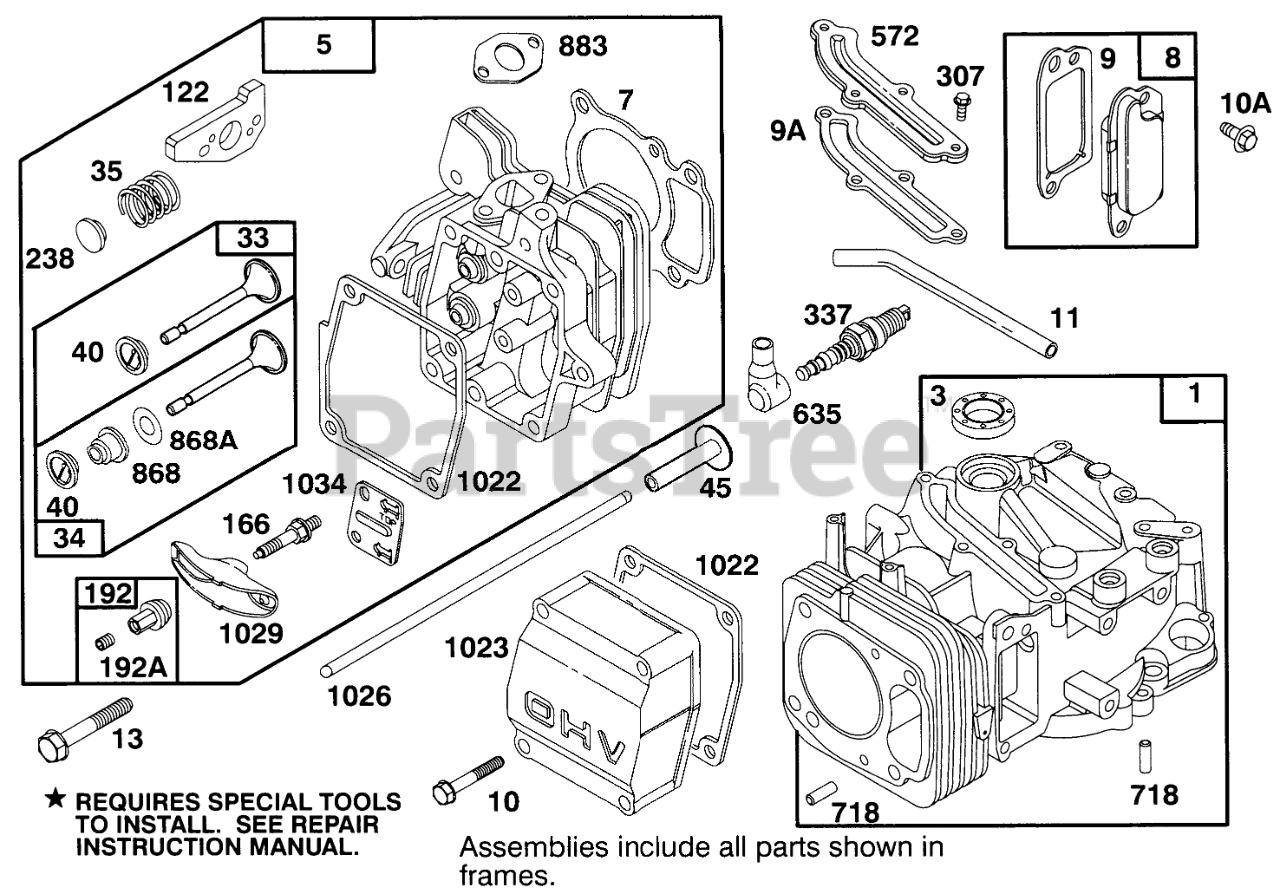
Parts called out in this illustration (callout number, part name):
1	CYLINDER ASSEMBLY
3	SEAL - OIL
5	CYLINDER HEAD
7	CYLINDER HEAD GASKET
8	Breather Assy
9	BREATHER GASKET
9A	GASKET-BREATHER
10	HEX HEAD SCREW
10A	HEX HEAD SCREW
11	TUBE - BREATHER
13	CYLINDER HEAD SCREW
33	EXHAUST VALVE
34	INTAKE VALVE
35	VALVE SPRING
40	SPRING RETAINER
45	VALVE TAPPET
122	ADAPTER ASSEMBLY
166	ROCKER ARM STUD
192	NUT - HEX SPECIAL
192A	SCREW SET
238	VALVE CAP
307	SCREW - SEM
337	PLUG-SPARK
572	BAFFLE - CYCLINDER
635	SPARK PLUG ELBOW
718	DOWEL - SLEEVE
868	SealAssy-Valve
868A	Seal-Valve
883	EXHAUST GASKET
1022	ROCKER COVER GASKET
1023	COVER - VALVE
1026	PUSH ROD
1029	ROCKER ARM
1034	PUSH ROD GUIDE
